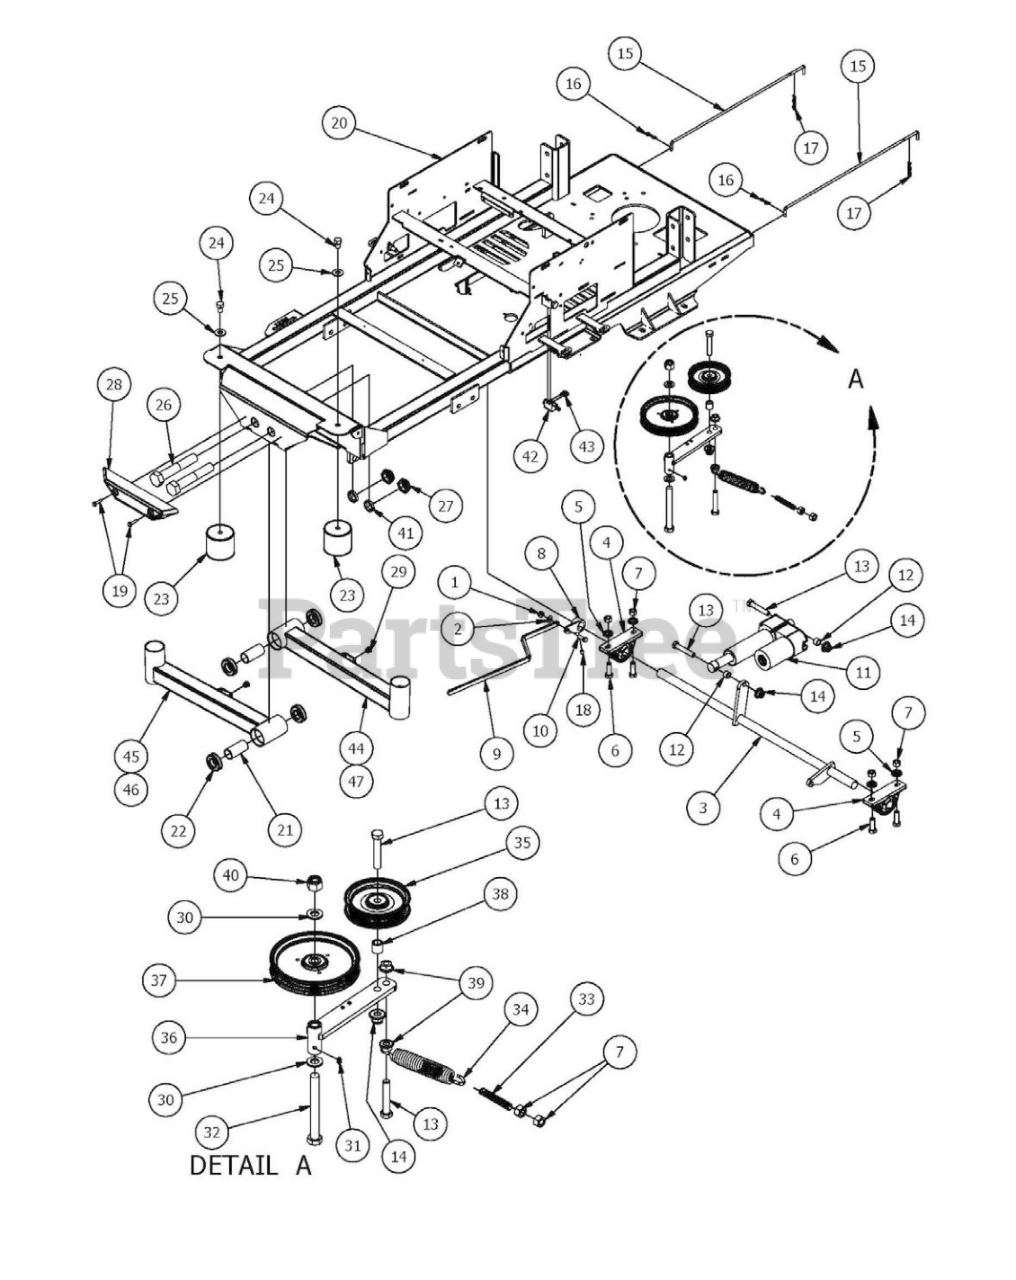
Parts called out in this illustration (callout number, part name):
1	5/16-18 Nylon Flange Nut
2	.360 ID Plastic Washer
3	Actuator Bar-ZT
4	pillow block 2bolt sealmaster
5	1/2" Lock Washer Zinc
6	1/2" x 1 1/2" Hex Bolt
7	1/2" Hex Nut
8	Height Indicator Lever
9	Height Indicator Bar
10	5/16" x 1" Bolt
12	1/2 x 1/2 Spacer
13	1/2" x 2 3/4" Hex Bolt
14	1/2-13 Nylon Flange Nut
15	ZT Neutral level rod 2011
17	Neutral Rod Clip
18	5/16 Set Screw
19	1/4 x 1 Hex Head Tek screw
20	2017 Maverick Frame
21	2016 Front Bearing Spacer
22	Caster Bearing 2016 - 1641 Bearing
23	Vibration Mount- Red Dot
24	1/2" x 3/4" Hex Bolt
25	1/2" Washer (Grade 8)
26	1-14 x 5.5 Hex Bolt Grade 8 Zinc Yellow
27	1" Fine Thread 1/2 Nylock Nut
28	Front Bumper
29	5/8 Round Insert
30	.630 ID Plastic Washer
31	1/4" Press in Grease Fitting
32	5/8" x 5 1/2 Hex Bolt
33	All Thread-Pump Idler Tensioner
34	2015 Deck Idler Spring
35	4 3/4" Idler Pulley
36	Deck Idler
37	5-3/4 Idler Pulley 5/8 Bore
38	Spacer 3/4 OD x 1/2 ID x 3\4 Length
39	1/2" Flange Nut
40	5/8 Std NC Nylock Nut
41	1" x .25" Spacer
42	Safety Switch
43	12-24x 1/2 HWH Bolt
44	2017 Maverick Suspension Arm-Long-Left
45	2017 Maverick Suspension Arm-Long-Right
46	Front Arm Assembly - Short (Right) (48" Deck Only)
47	Front Arm Assembly - Short (left) (48" Deck Only)
